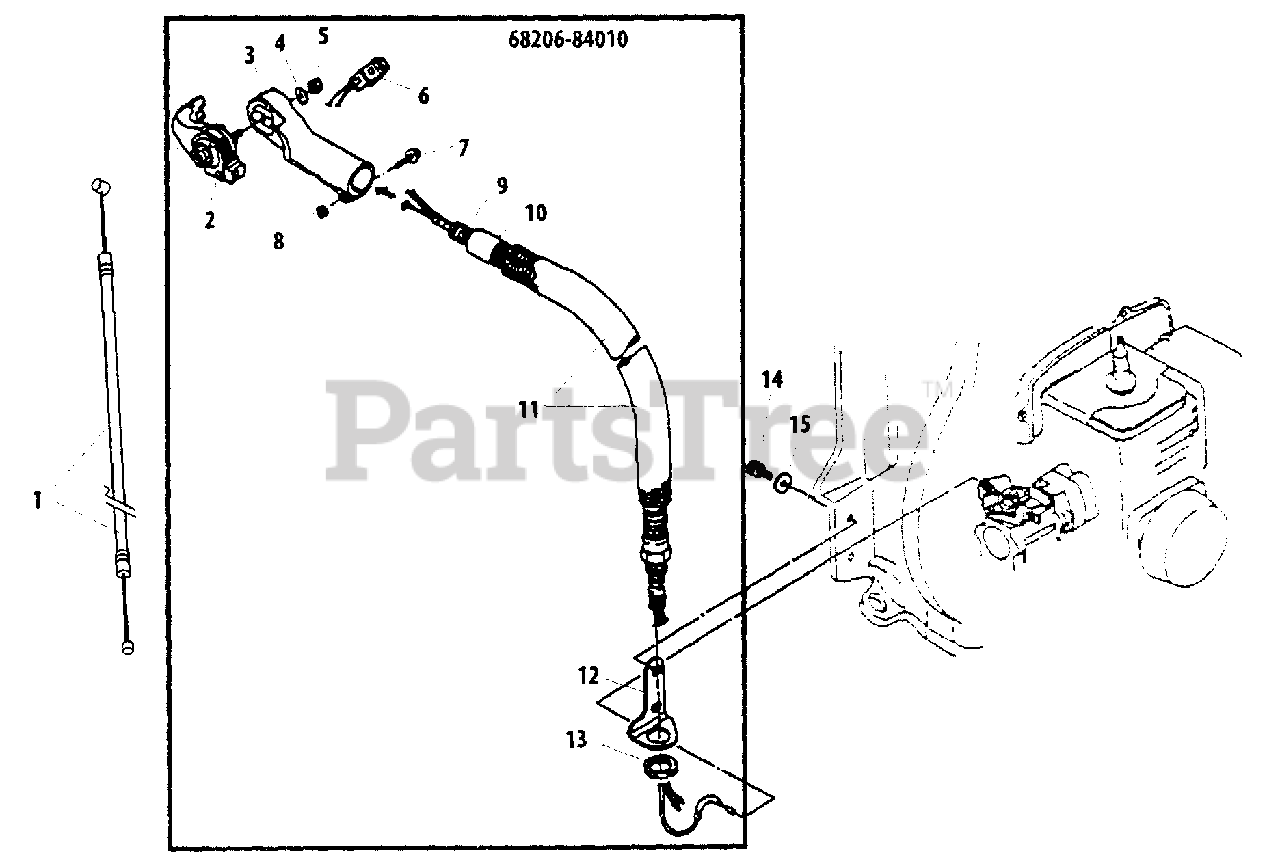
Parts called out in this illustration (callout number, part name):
1	CABLE, THROTTLE
2	CONTROL, THROTTLE
3	GRIP
4	WASHER 5 MM
5	U-NUT M5
6	SWITCH, ON-OFF
7	BOLT M5×16
8	NUT M5
9	TUBE, FLEXIBLE
10	FLEXIBLE TUBE, METALLIC
11	TUBE, OUTER FLEX
12	BRACKET
13	NUT
14	BOLT, ADHESIVE M5×14
15	WASHER Ø15ר5.2×1.6
68206-84010	THROTTLE LEVER ASSY
